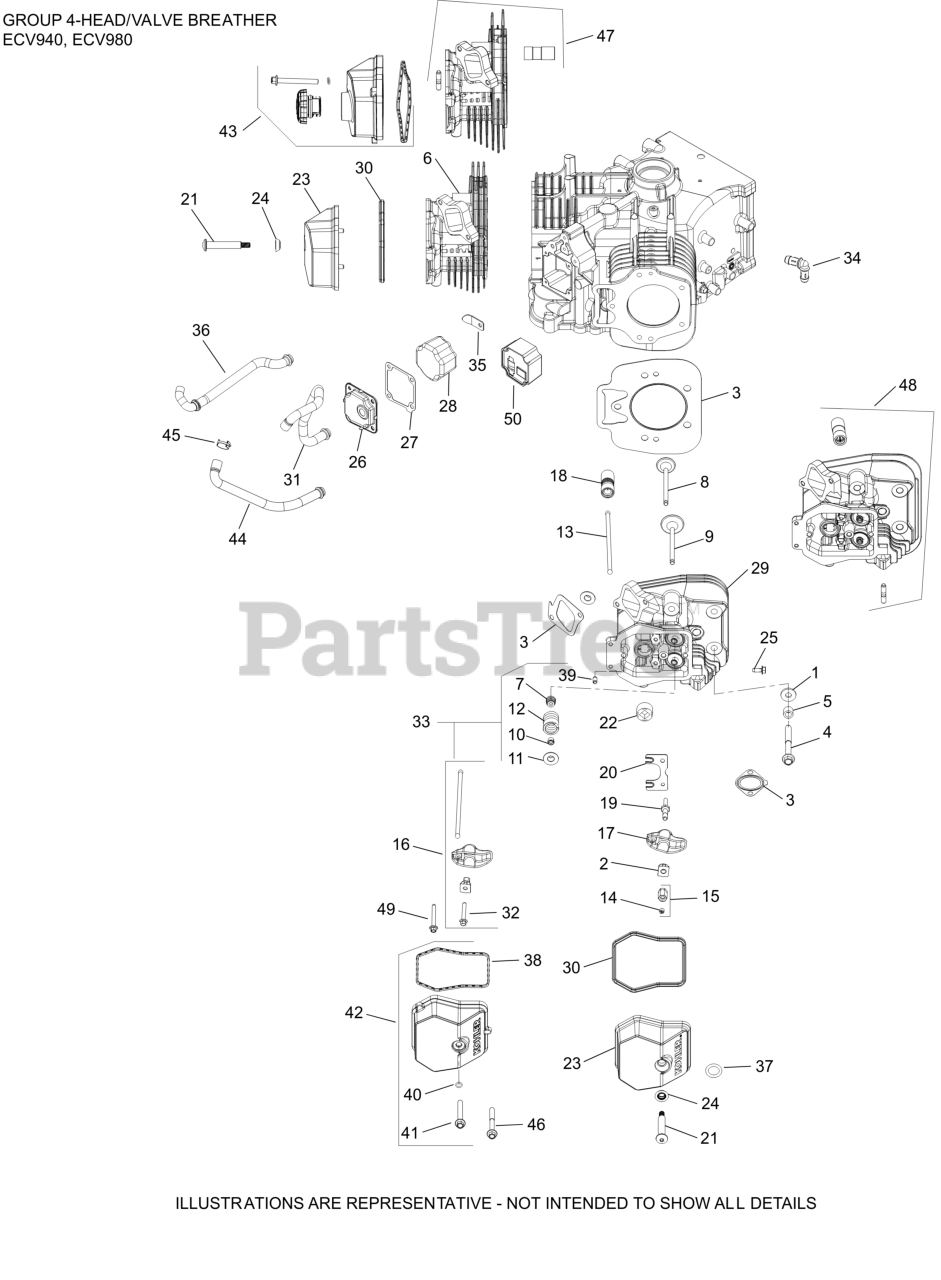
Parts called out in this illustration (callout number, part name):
1	WASHER, FLAT 13/32"
2	PIVOT, ROCKER ARM
3	KIT, CYLINDER HEAD GASKET
4	SCREW, FLG M10X1.5X90
7	SEAL, VALVE BAND
8	VALVE, EXHAUST
9	VALVE, INTAKE
10	KIT, RETAINER
11	CAP, VALVE SPRING
12	SPRING, VALVE
13	ROD, PUSH
17	ARM, ROCKER
18	LIFTER, HYDRAULIC VALVE (SERVICE)
22	PLUG, PIPE 3/4 NPTF SQUARE
25	SCREW, THREAD FORMING
26	KIT, BREATHER ASSEMBLY
27	GASKET, BREATHER
38	SEAL, ALUMINUM VALVE COVER (BLUE)
39	PIN, ROLL
40	O-RING, VALVE COVER SCREW
42	KIT,VALVE CVR (NO FILL)-USE 62 096 50-S
42	KIT, VALVE COVER ASSEMBLY
44	CLAMP, SPRING HOSE
45	HOSE, BREATHER (ETB)
46	SCREW, HEX FLANGE
47	KIT, #1 CYLINDER HEAD COMPLETE
48	KIT, #2 CYLINDER HEAD COMPLETE
49	SCREW, HEX FLANGE
50	FILTER, BREATHER
